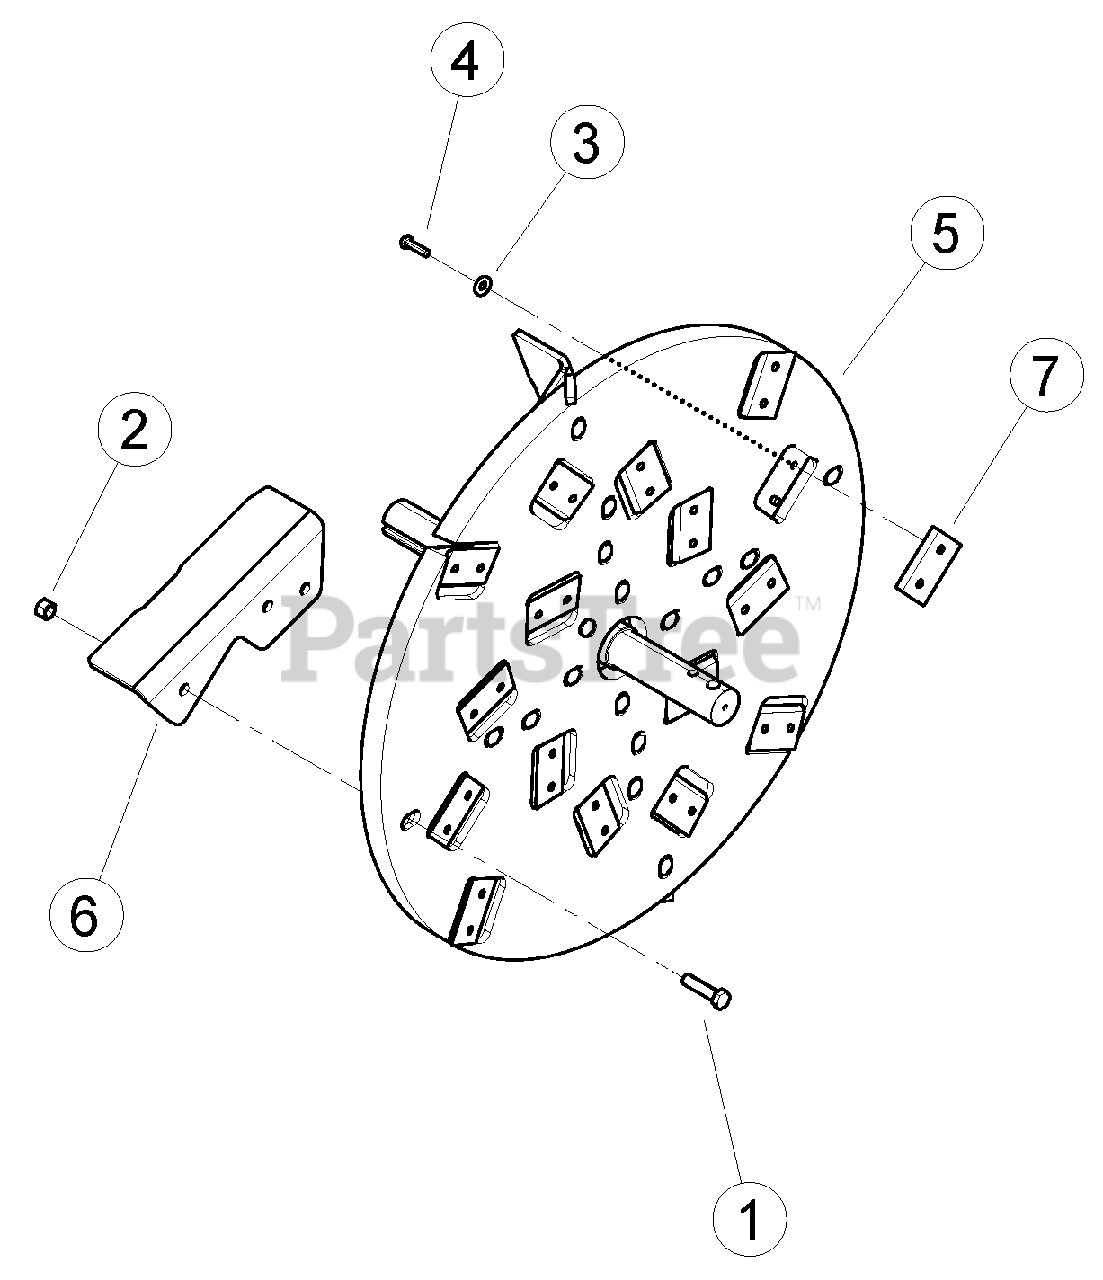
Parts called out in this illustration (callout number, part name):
1	BOLT, 1/2-13 X 2 GR5 HEX CAPSCREW
2	NUT, 1/2" CENTERLOCK GRB ZP
3	WASHER, 5/8 SAE HARDENED
4	BOLT, M16 X 2.0 X 30 HEX HD W/ PATCH
5	KIT, BIG CHIPPER FORMED PADDLES
6	ASSEMBLY, 9 INCH CHIPPER ROTOR
7	KIT, CHIPPER BLADE
